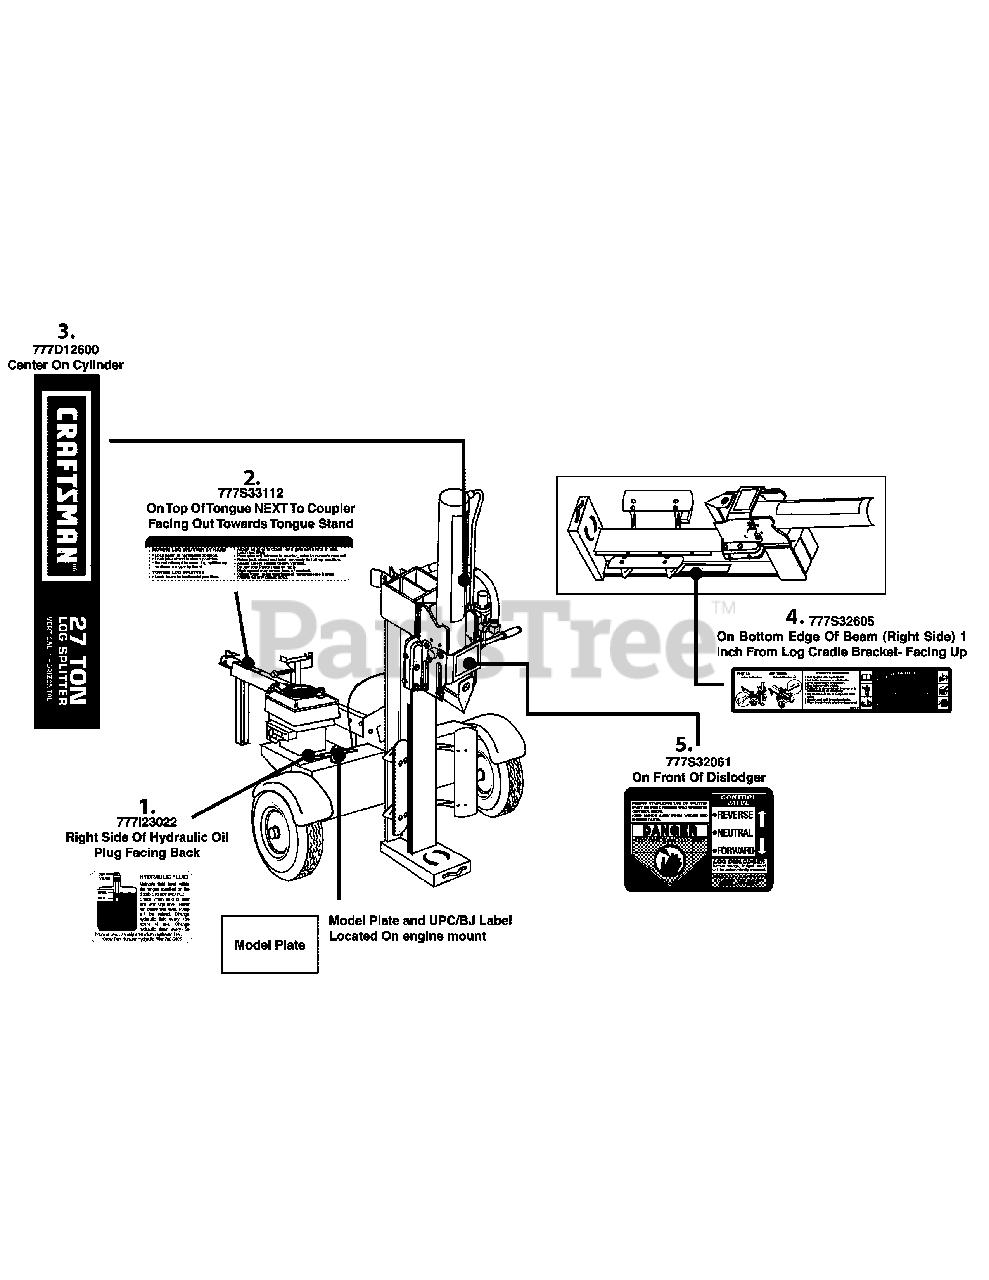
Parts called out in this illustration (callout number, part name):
1	LABEL-LOGSPLITTER HYDRAULIC FLUID
2	LABEL-LOGSPLITTER TOW WARNING
3	LABEL-LOGSPLITTER CYL CRAFTSMAN
4	LABEL-BEAM DNGR INSTR
5	LABEL-CNTRL VALVE
